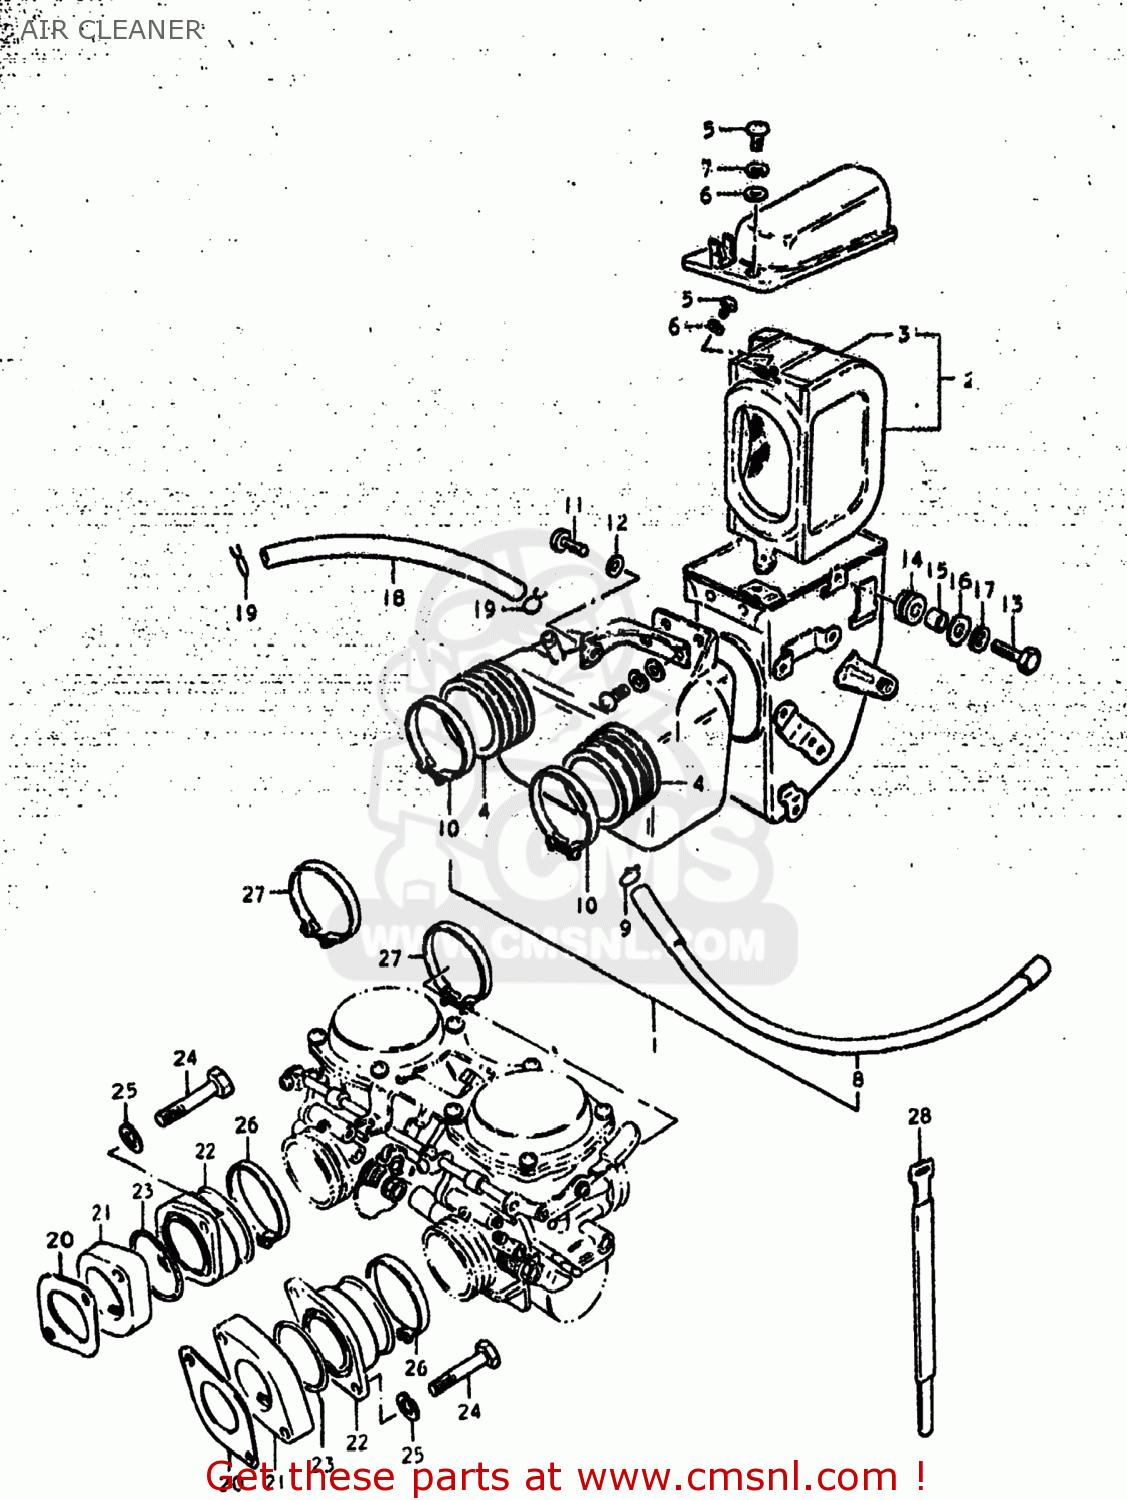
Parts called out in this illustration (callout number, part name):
1	CLEANER ASSEMBLY,AIR
2	FILTER ASSY
3	FILTER
4	HOSE,AIR CLEANER INLET
5	SCREW
6	WASHER
7	LOCK WASHER
8	HOLDER,FILTER
9	HOSE,AIR CLEANER
10	CLAMP
11	SCREW
12	WASHER 6MM
13	BOLT
14	CUSHION
15	SPACER
16	WASHER
17	LOCK WASHER
18	HOSE
19	CLIP
20	GASKET,CARBURETOR (NAS)
21	INSULATOR,CARBURETOR
22	PIPE,INTAKE
23	O-RING (D:2.4 ID:39.7)
24	BOLT
25	LOCK WASHER
26	CLAMP
27	CLAMP
28	CLAMP
